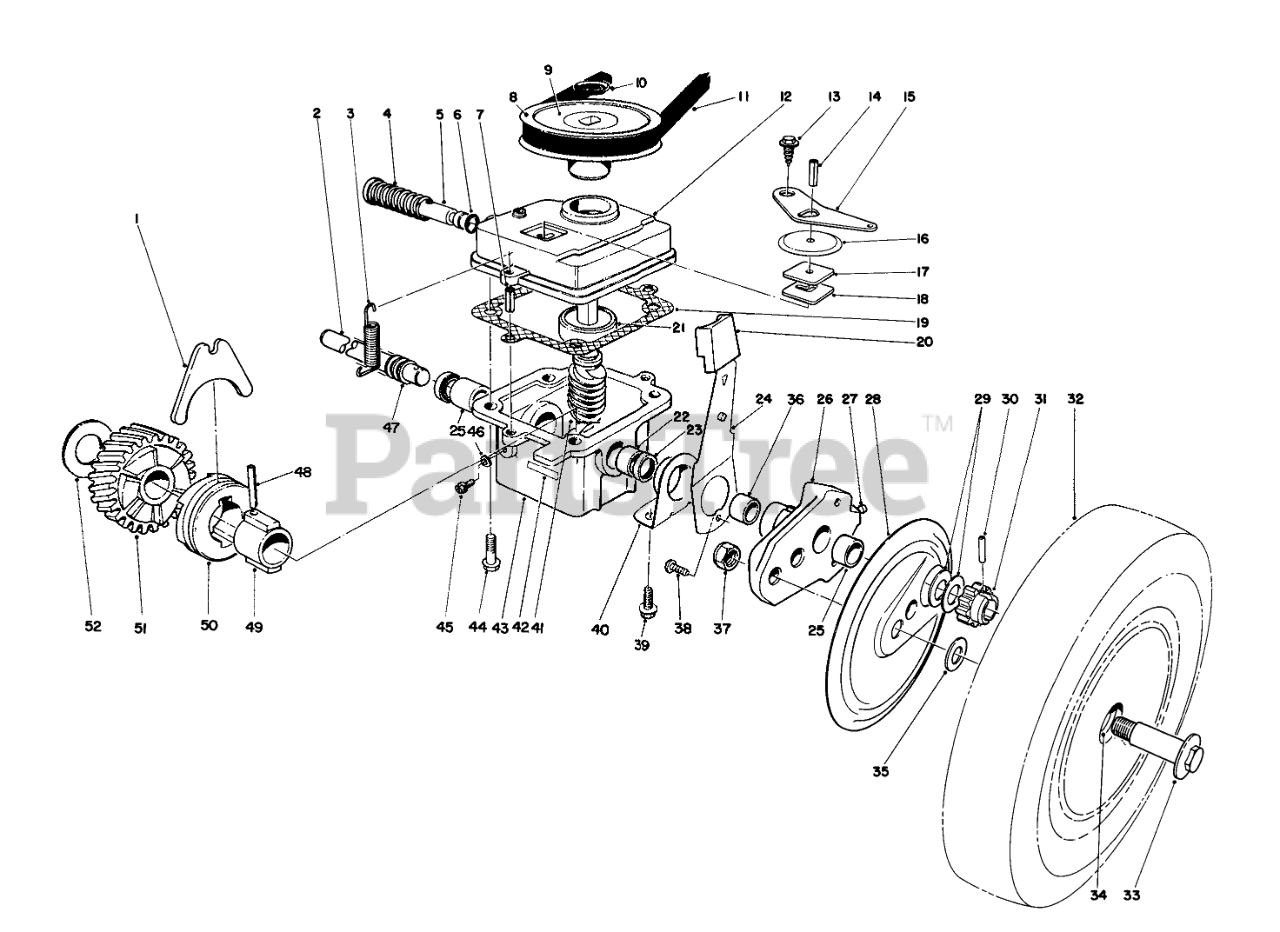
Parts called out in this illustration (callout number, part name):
1	SHIFTER FORK
2	DRIVE SHAFT
3	TENSION SPRING
4	SPRING
5	SHIFTER ROD
6	O-RING
7	3/16 X 1/2 ROLL PIN
8	PULLEY
9	DECAL
10	PUSH-ON 93-3236
11	V BELT
12	GEAR CASE COVER
13	Screw
14	SPIROL PIN H D
15	SHIFTER ARM
16	DUST COVER
17	DUST FILTER
18	LATCH PLATE
19	GASKET
20	KNOB-ARM
21	BEARING
22	BUSHING
23	SEAL-OIL
24	SPRING ARM ASSY-FRONT
25	BUSHING
26	Arm-Pivot (Incl. Ref. #25, 27 & 36)
27	FITTING-GREASE
28	WHEEL COVER
29	THRUST WASHER
30	Pin
31	PINION GEAR 15T
32	Wheel, Tire & Gear Assy (Incl. Ref. #34)
33	BOLT-WHEEL
34	BUSHING
35	WASHER
36	BUSHING
37	Nut
38	SCREW
39	SCREW-HWHTF
40	END CAP
41	Worm Shaft & Gear (Incl. Ref. #51)
42	DECAL
43	Gear Case (Incl. Ref. #22, 23 & 25)
44	Screw
45	NYLON SCREW
46	FILL PLUG GASKET
47	COVER-SHAFT, DRIVE
48	COIL PIN
49	SLEEVE
50	CLUTCH JAW
51	Gear-Helical
52	THRUST WASHER
